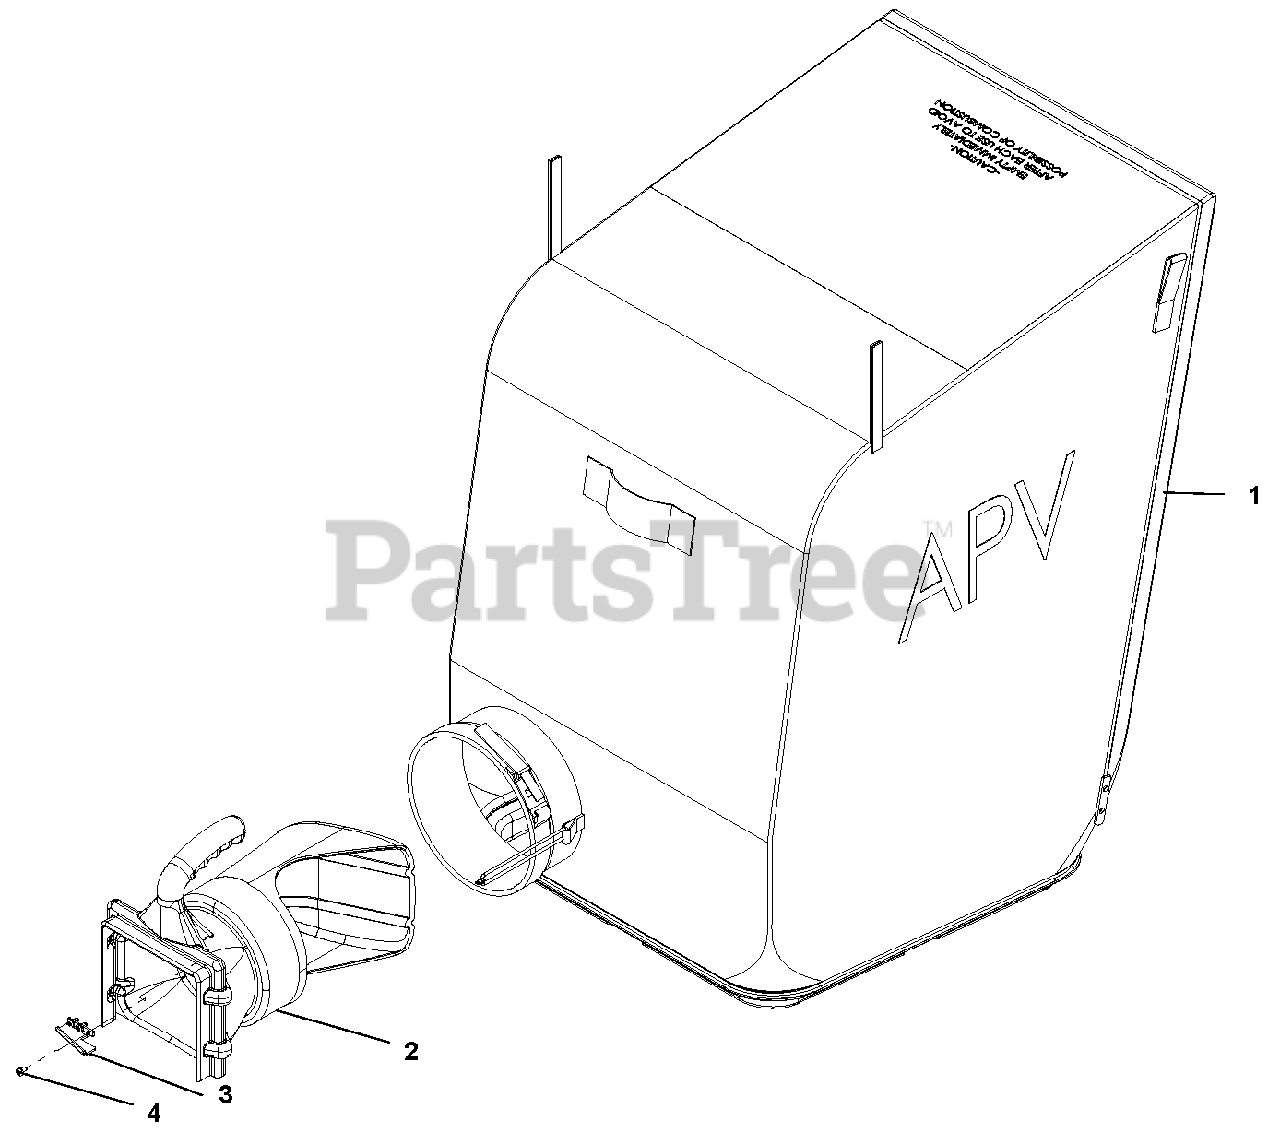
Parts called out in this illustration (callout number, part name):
1	Bag, APV, Black Poly Felt
2	APV Bag Discharge Chute, '07 Parker Red
3	Switch Depression Bracket
4	Screw, Steel, B 10 X .37 NI
